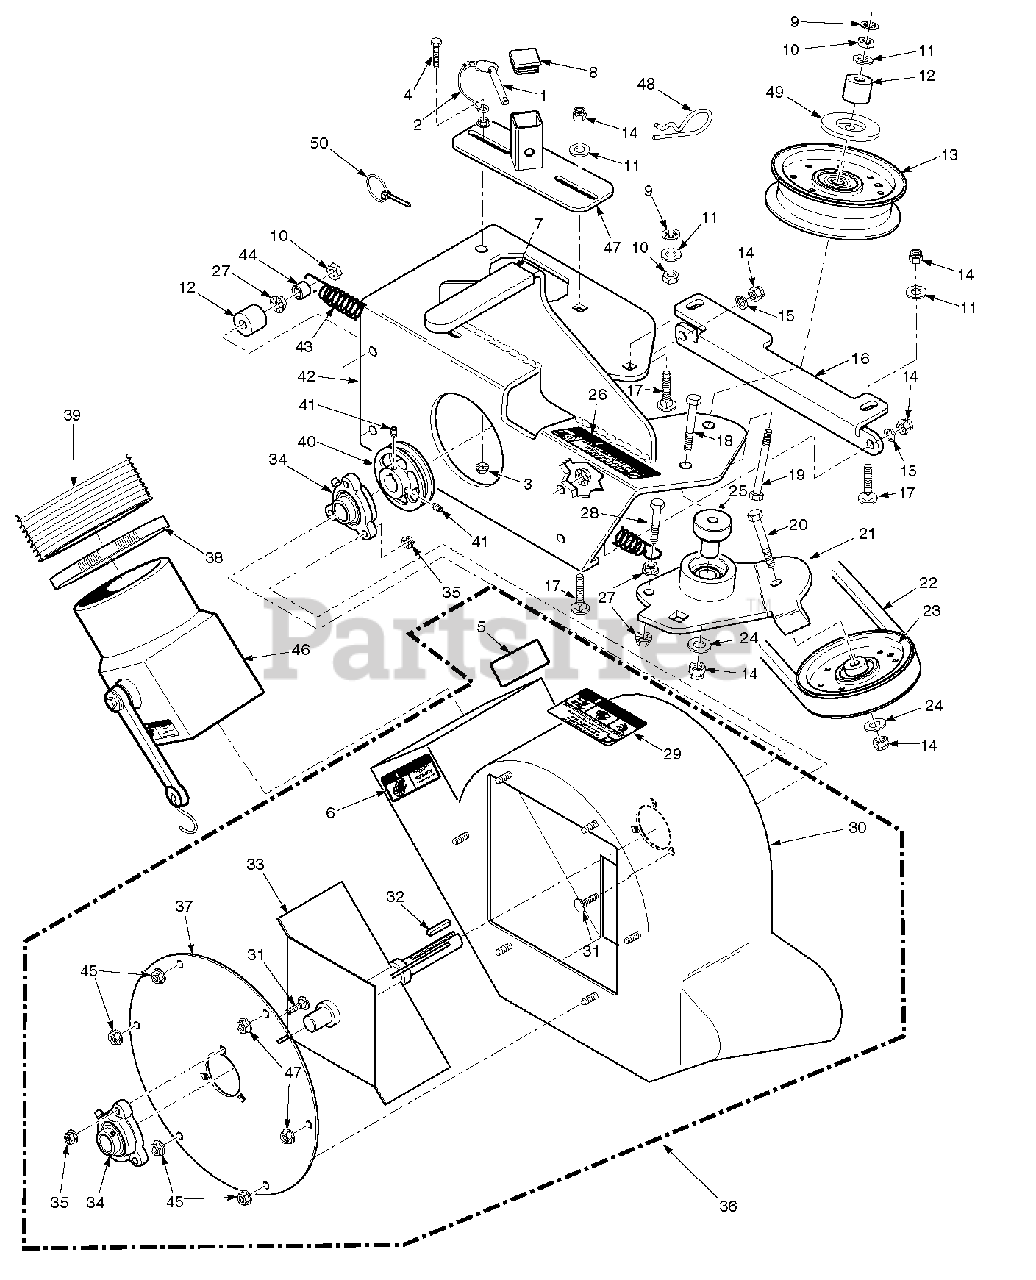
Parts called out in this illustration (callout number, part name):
1	Pin, Ring 2-1/4" Long
2	Lanyard, Deck Height Pin
3	Nut, Serr. Flange 1/4-20
4	Bolt, Hex Head 1/4-20 x 1-1/4"
5	Decal, Blower
6	Decal, Rotating Blower
7	Grip, Blower Lever
8	Cap, Square
9	Nut, Push On 3/8 Thread
10	Lock Nut, 3/8-16
11	Flatwasher, 3/8-.391 x .938 x .105
12	Spacer
13	Pulley, Idler 4" Dia.
14	Nut, Elastic Stop 3/8-16
15	Lockwasher, 3/8-16
16	Plate, Catcher Mounting
17	Bolt, Carr. 3/8-16 x 1-1/2"
18	Bolt, Hex Head 3/8-16 x 3" - 52"
19	Bolt, Hex Head 3/8-16 x 3-1/2"
20	Bolt, Hex Head 3/8-16 x 1-3/4"
21	Idler Arm Assembly
22	Belt, GC-STC
23	Pulley, 3-1/2" O.D., GC-STC
24	Washer, 3/8 Hardened
25	Pivot, Idler
26	Decal, Belt Cover
27	Nut, Serr. Flange 3/8-16
28	Bolt, Hex Head 3/8-16 x 1-1/2 Gr. 8
29	Decal, Danger
30	Blower Housing Weldment
31	Bolt, Carr. 5/16-18 x 3/4" Gr. 5
32	Key, 1/4 x 1/4 x 1-1/2"
33	Fan Weldment
34	Bearing Assembly
35	Nut, Elastic Stop 5/16-18
36	Blower Housing Assembly, GC-STT
37	Cover, Blower Housing
38	Clamp, 8-5/8" Max Dia.
39	Hose, 8.00" Dia. x 53" Long
40	Pulley, 4-3/4" O.D. - 1" Bore
41	Set Screw, 5/16-18 x 3/8"
42	Frame, Blower Mount
43	Spring, Main Drive
44	Spacer
45	Nut, Serr. Flange 5/16-18
46	Adapter w/Strap
47	Receiver Weldment, Mounting Post
48	Hair Pin Cotter, .177 x 3-1/4"
49	Dust Shield
50	Quick Pin, 5/16" Dia.
